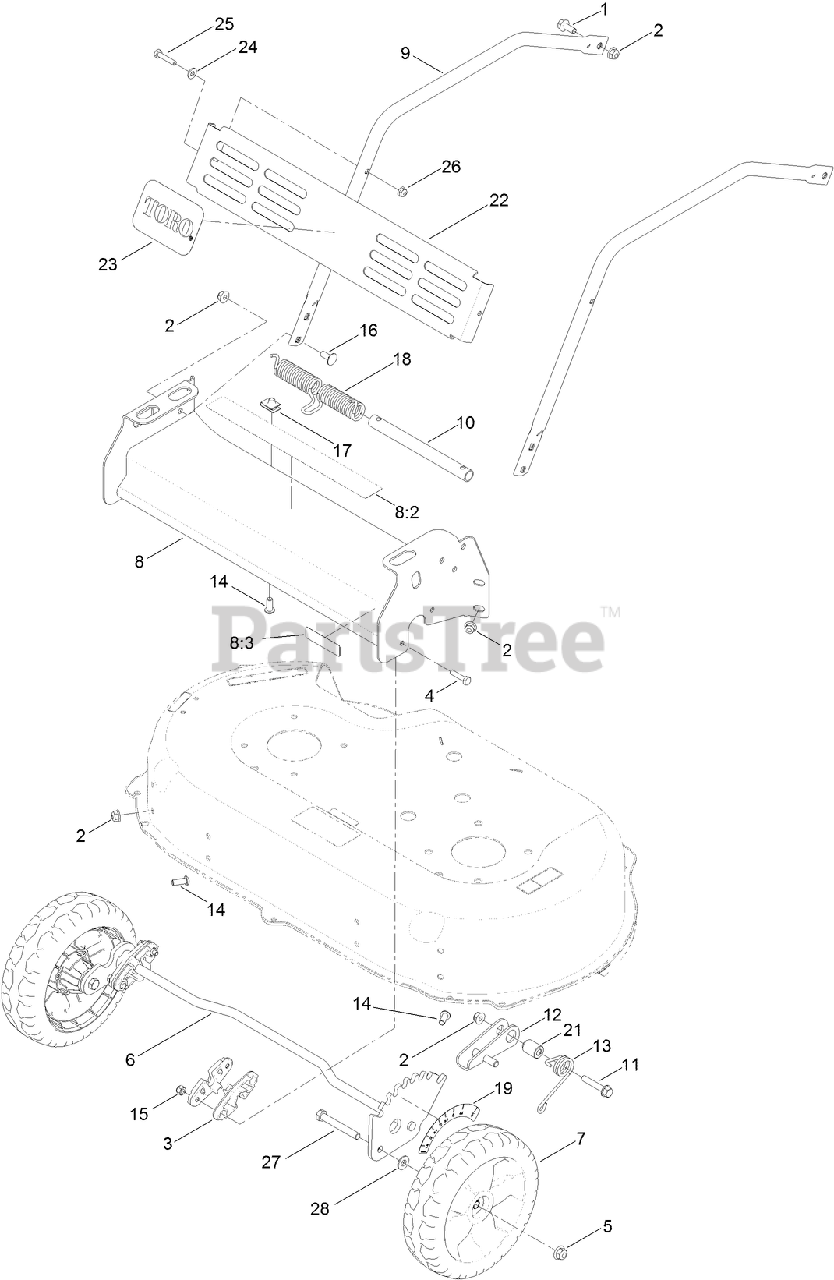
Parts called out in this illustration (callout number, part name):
1	SCREW-HHF
2	NUT-HF, NI
3	BUSHING-FRONT
4	SCREW-HH
5	NUT-HF, NI
6	AXLE-FRONT
7	WHEEL
8	FRONT BUMPER ASM
8:3	DECAL-WARNING
10	MANDRELL-SPRING
11	SCREW-HWH
12	LOCK-HEIGHT, ADJUSTMENT
13	SPRING-TORSION
14	SCREW-HSBH
15	NUT-LOCK, NI
16	SCREW-CARR
17	NUT-U
18	SPRING-TORSION
19	DECAL-HOC, FRONT
21	SPACER
24	WASHER-FLAT
25	SCREW-HH
26	NUT-HF
27	SCREW-HH
28	SPACER-COVER, WHEEL
